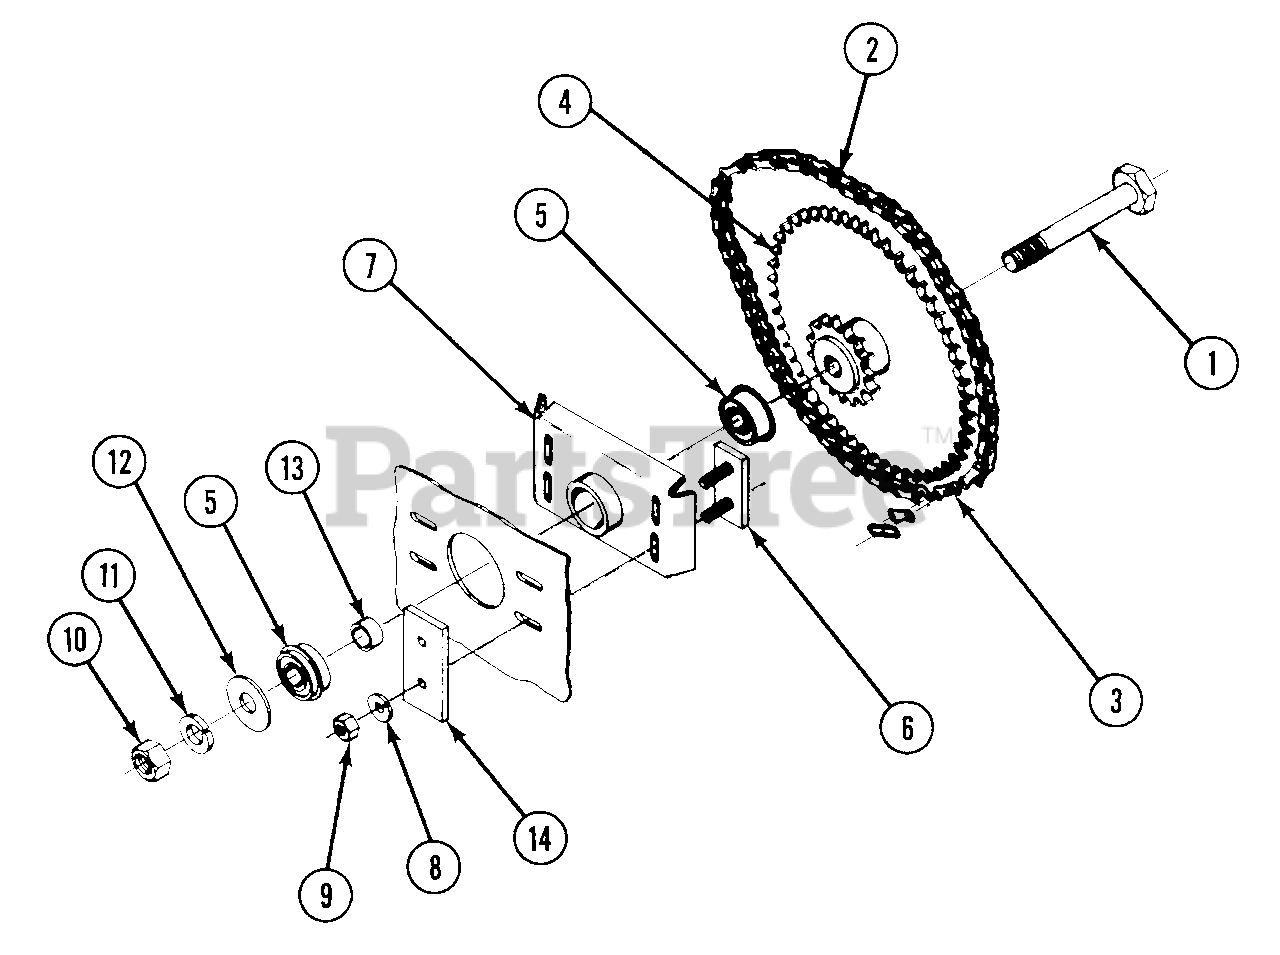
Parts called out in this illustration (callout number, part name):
1	JACK SHAFT BOLT, SPECIAL, 3/4-10 THRD
2	#40 CHAIN
3	MASTER LINKS #40 CHAIN
4	DOUBLE SPROCKET, #50-15 & #40-60
5	BEARINGS .750 BORE
6	DOUBLE BOLT WELDMENT, 3/8-16
7	JACK SHAFT IDLER WELDMENT
8	LOCKWASHER, 3/8 HEAVY, SPLIT SPRING
9	LOCKNUT, HEX, 3/8-16
10	NUTS HEX, 3/4-10
11	LOCKWASHER, 3/4 STD, SPLIT SPRING
12	WASHER, 3/4 STD, FLAT
13	BEARING SPACER
14	DOUBLE WASHER
